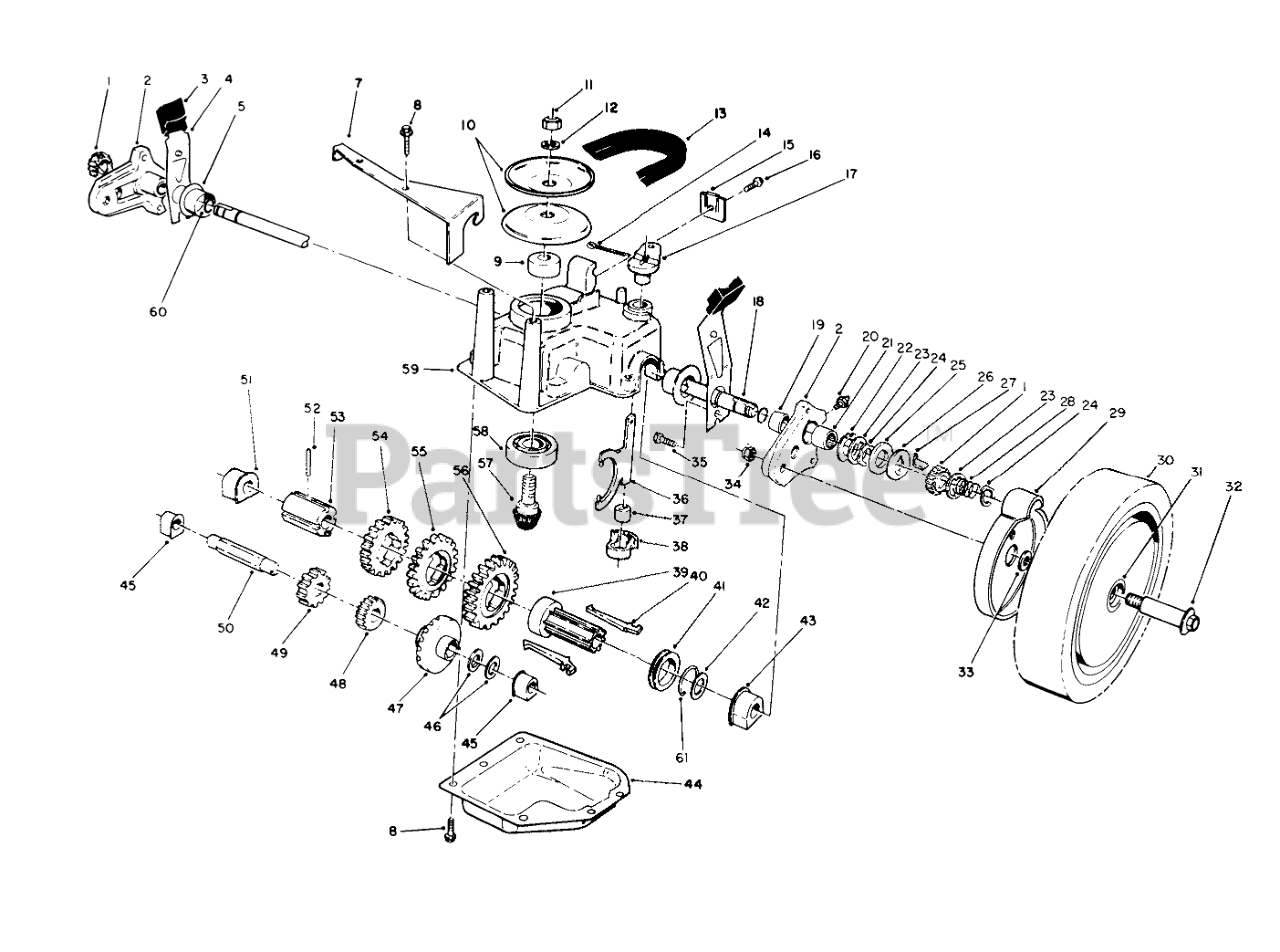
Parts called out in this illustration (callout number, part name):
1	GEAR-PINION
2	Pivot Arm Assembly (Incl. Ref. #19-21)
3	KNOB-ARM
4	SPRING ARM ASM SP
5	CAP-END
7	Bracket-Guide
8	SCREW-HWHTF
9	SPACER
10	Pulley Half
11	NUT-HEX
12	WASHER-FLAT
13	V-BELT E
14	PIN-COTTER
15	Cable Clamp
16	SCREW-HWHTF
17	SHIFT LEVER
18	SHAFT-OUTPUT
19	BUSHING
20	FITTING-GREASE
21	BEARING-ROLLER
22	WASHER-ARM, PIVOT
23	WASHER-THRUST, KEYED
24	RING-CLIP, LOCKING
25	RING-FRICTION
26	WASHER-CLUTCH
27	KEY-ROCKING, LH
28	SPRING-COMPRESSION
29	COVER-WHEEL
30	Wheel Tire & Gear Assembly (Incl. Ref. #32)
31	BUSHING
32	WHEEL BOLT
33	SPACER-COVER, WHEEL
34	Nut
35	SCREW-HWH
36	YOKE-SHIFT
37	BUSHING-YOKE
38	RETAINER-FORK, SHIFT
39	SLEEVE-KEY, SHIFT
40	KEY-SHIFT
41	COLLAR-SHIFT
42	WASHER-PLAIN
43	BUSHING-OUTPUT
44	Cover-Gearcase
45	BUSHING
46	WASHER-THRUST
47	Gear-Bevel
48	PINION-20T
49	PINION-25T
50	SHAFT-INTERMEDIATE
51	BUSHING
52	PIN-SPRING
53	SLEEVE-GEAR
54	GEAR-39T
55	GEAR-44T
56	GEAR-49T
57	Gear-Pinion
58	BEARING-BALL
59	CASE-GEAR, UPPER
60	O-RING
61	CLIP-SPRING
